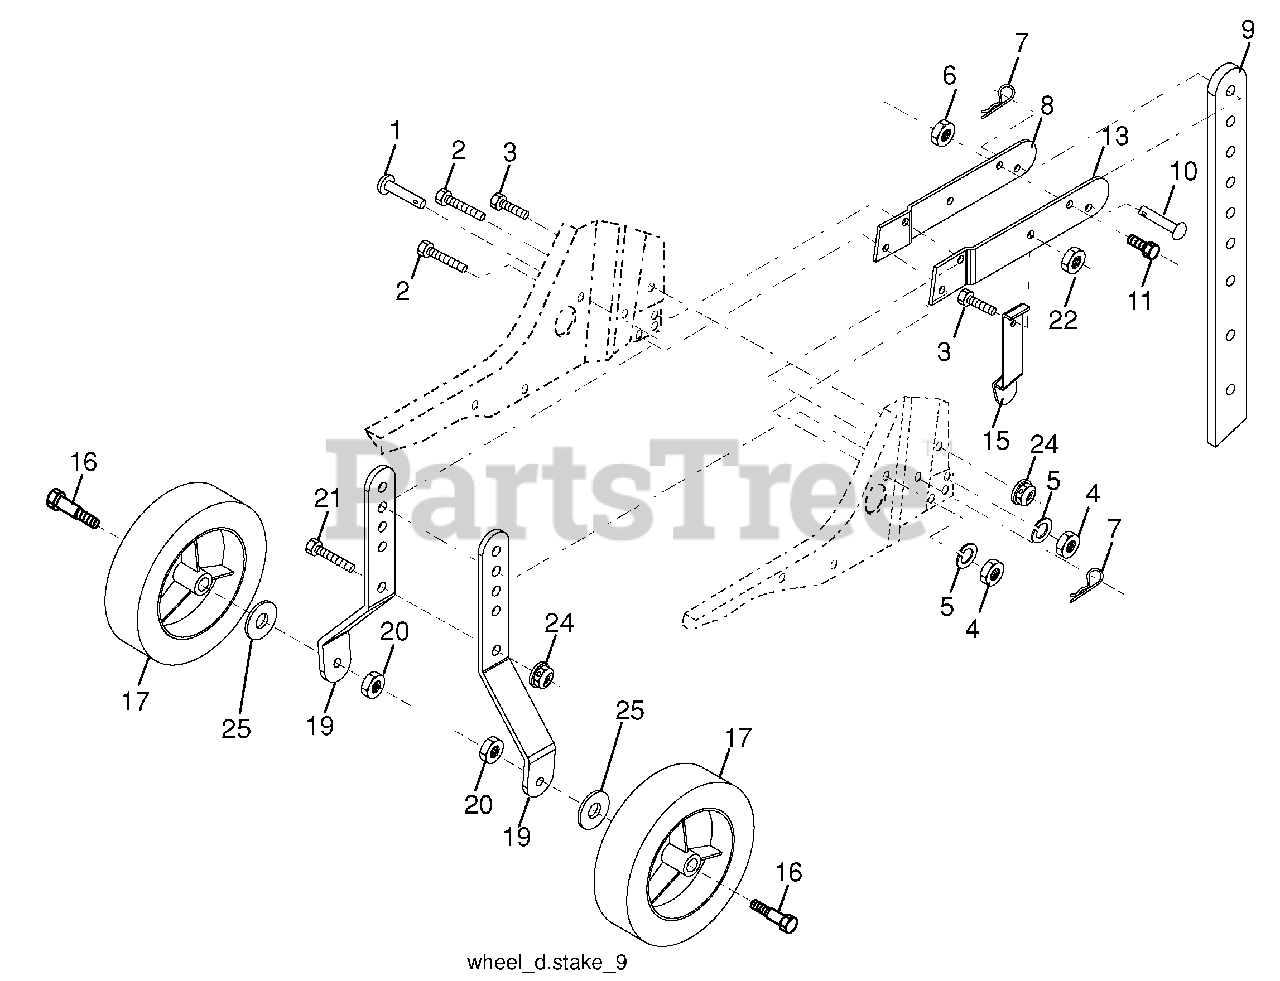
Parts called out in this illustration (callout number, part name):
1	Pin, Clevis
2	Bolt, Hex Head 5/16-18 x 1-1/4
3	Bolt, Hex Head 5/16-18 x 3/4
4	Nut, Hex 5/16-18
5	Washer, Lock 5/16
6	Locknut, w/washer 3/8-16
7	Clip, Hairpin
8	Support, Depth Stake, R.H.
9	Stake, Depth
10	Pin, Clevis
11	Bolt, Hex 3/8-16 x 1-3/4
13	Support, Depth Stake, L.H.
15	Spring, Stake
16	Bolt, Shoulder
17	Wheel
19	Bracket, Wheel
20	Locknut, Crown 3/8-16
21	Bolt, Hex Head 5/16-18 x 1
22	Locknut, w/insert 5/16-18
24	Locknut, Flange 5/16-18 unc
25	Washer 17/32 x 7/8 x 16 Ga.
